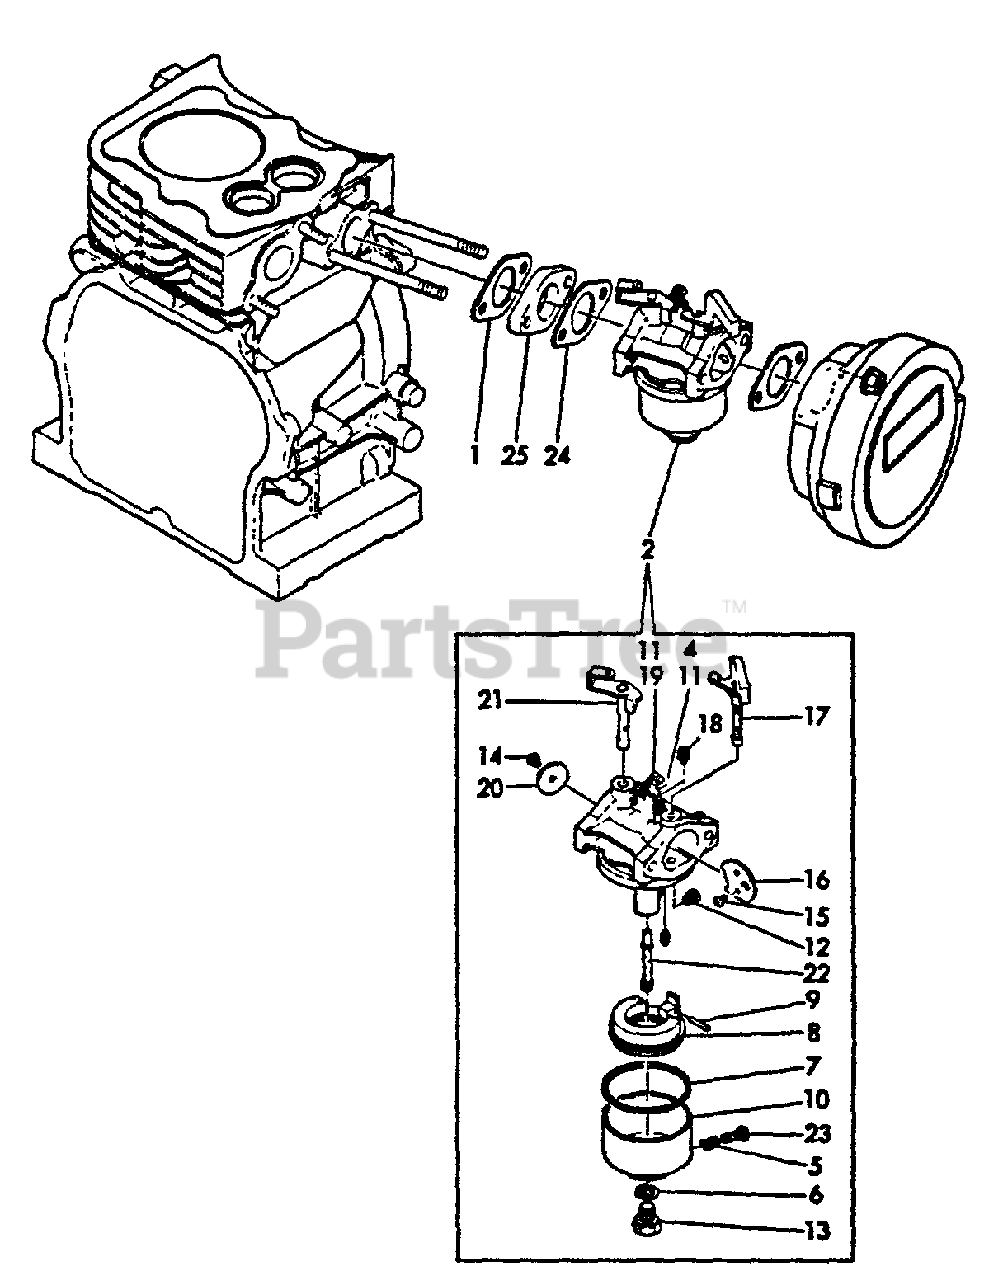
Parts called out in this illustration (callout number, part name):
1	GASKET, EXHAUST
2	CARBURETOR
4	SCREW, THROTTLE
6	WASHER
7	GASKET
8	FLOAT
9	PIN
10	BODY, FLOAT CHAMBER
11	SPRING
12	JET, MAIN
13	BOLT
14	SCREW
15	SCREW -- TAPPING
16	VALVE, CHOKE
17	SHAFT, CHOKE
18	JET, PILOT
19	SCREW
20	VALVE, THROTTLE
21	SHAFT, THROTTLE
22	NOZZLE, MAIN
23	SCREW
24	GASKET, INTAKE
25	GASKET, INTAKE
